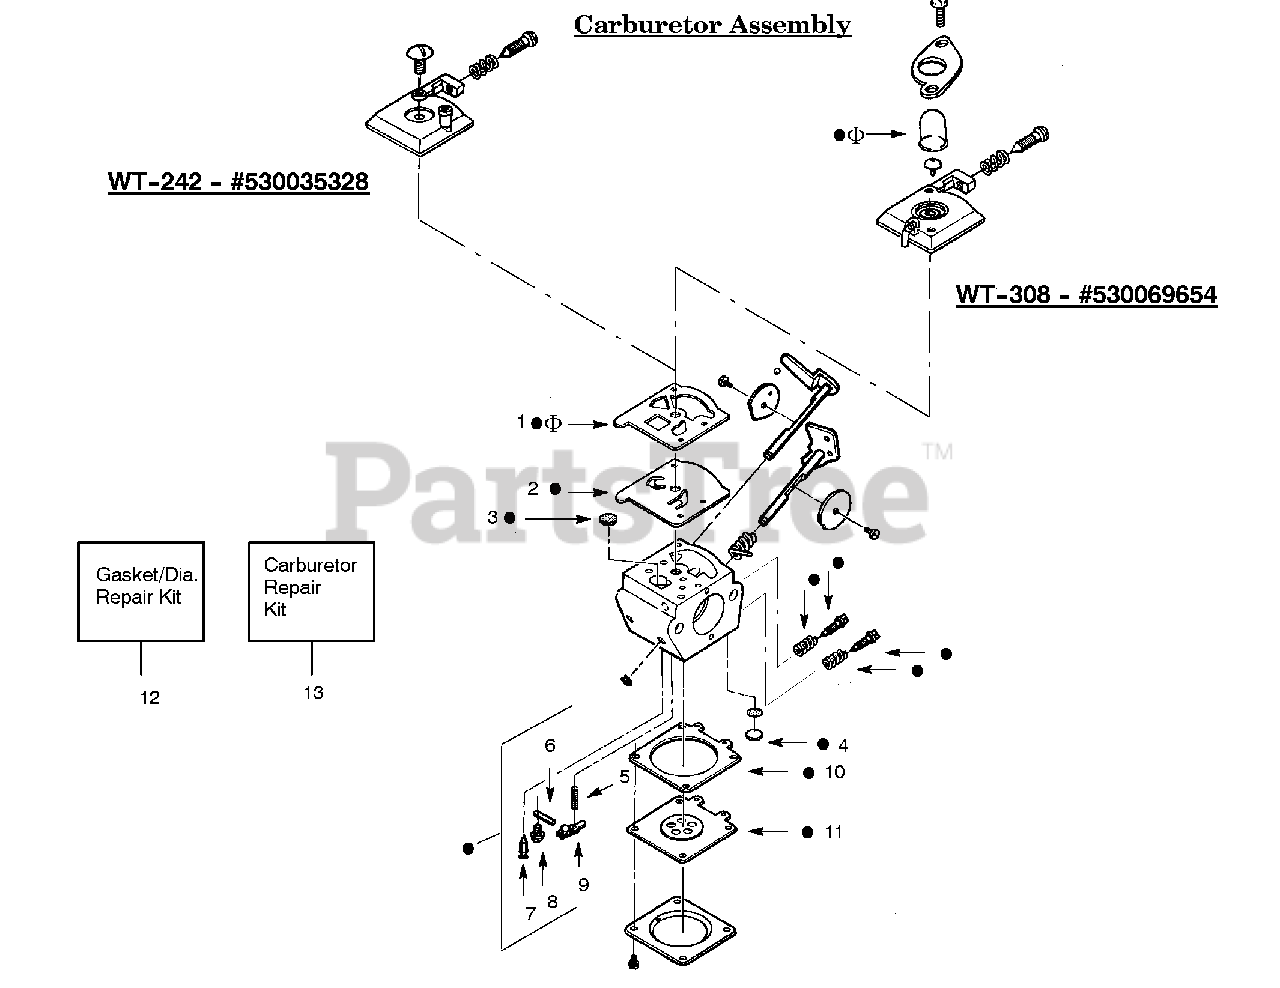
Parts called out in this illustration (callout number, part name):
1	Pump Gasket
2	Pump Diaphragm
3	Fuel Inlet Screen
4	Welch Plug
5	Metering Lever Spring
6	Metering Pin
7	Inlet Needle Valve
8	Metering Lever Pin Screw
9	Metering Lever
10	Metering Diaphragm Gasket
11	Metering Diaphragm
12	Gasket/Diaphragm Kit
13	Carburetor Repair Kit WT-242
13	Carburetor Repair Kit WT-308
